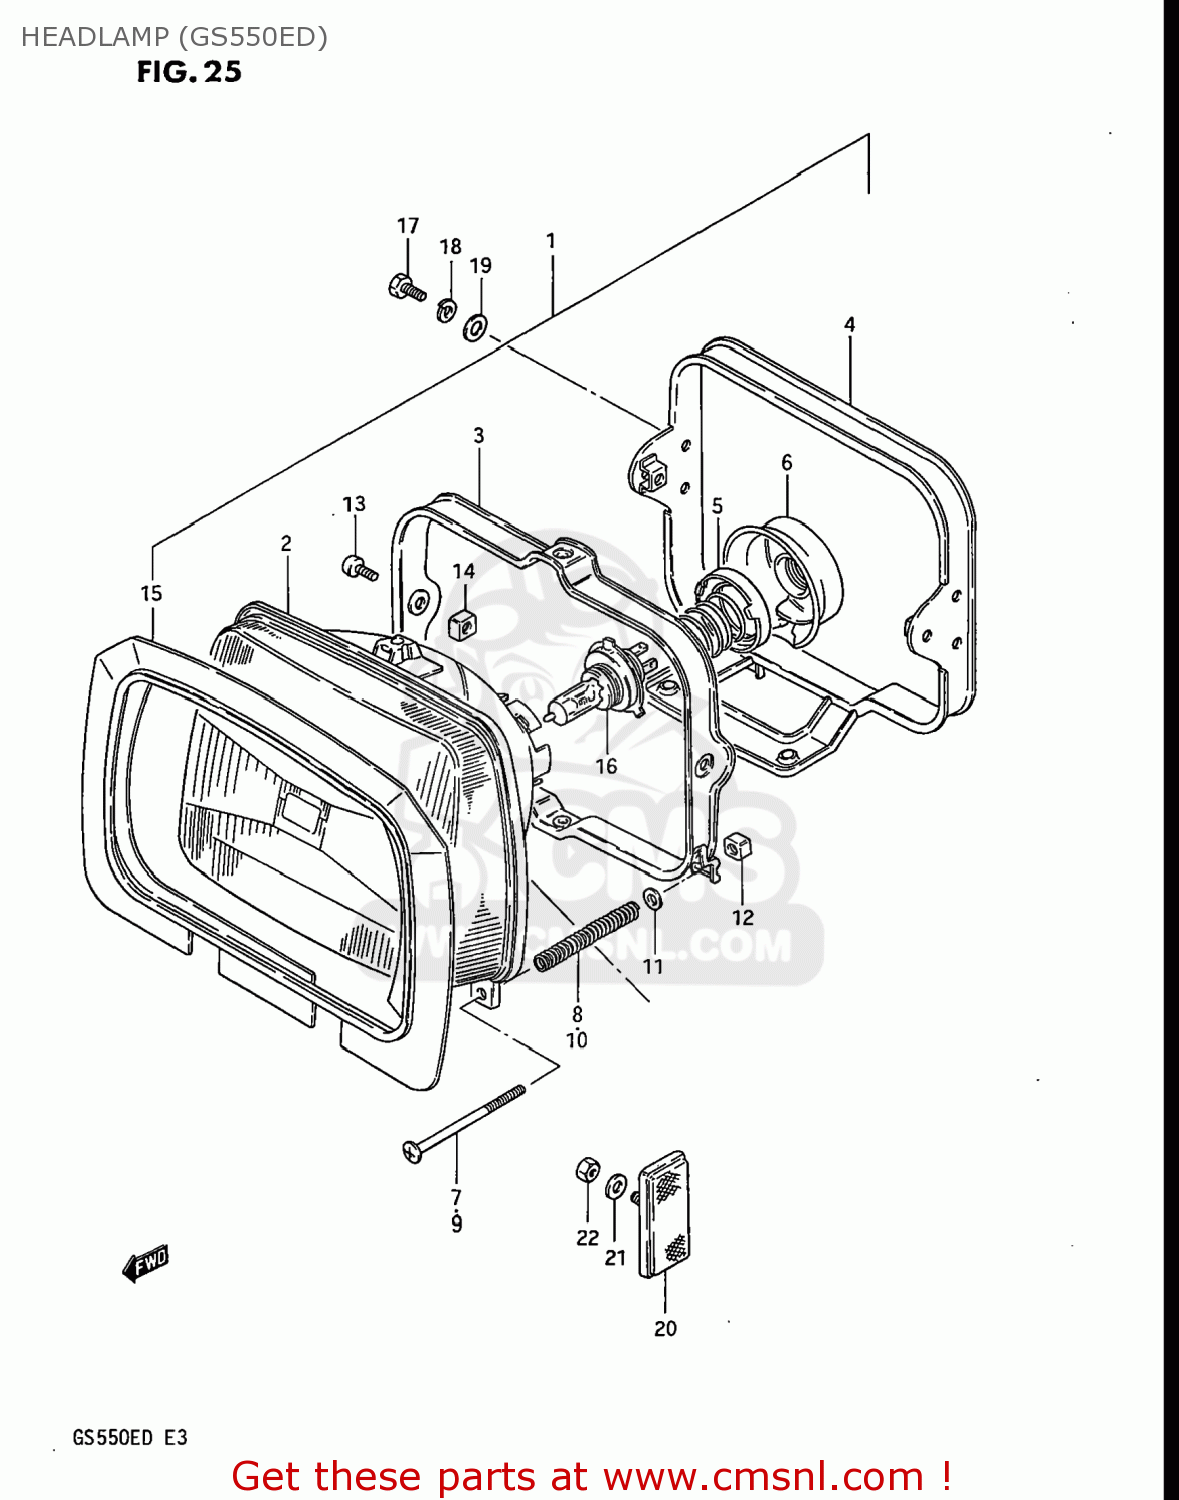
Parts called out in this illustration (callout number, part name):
1	HEADLAMP ASSEMBLY
2	LAMP UNIT
3	RING,MOUNTING
4	HOUSING
5	HOLDER
6	COVER,HEADLAMP SOCKET
7	SCREW,HEADLAMP ADJUST
8	SPRING
9	SCREW,HEADLAMP ADJUST
10	SPRING,HEADLAMP ADJUST
11	WASHER
12	NUT
13	SCREW
14	NUT
15	SHADE
16	BULB(12V60/55W,H4)
17	BOLT
18	LOCK WASHER
19	WASHER
20	REFLEX REFLECTOR ASSEMBLY
21	WASHER
22	NUT
